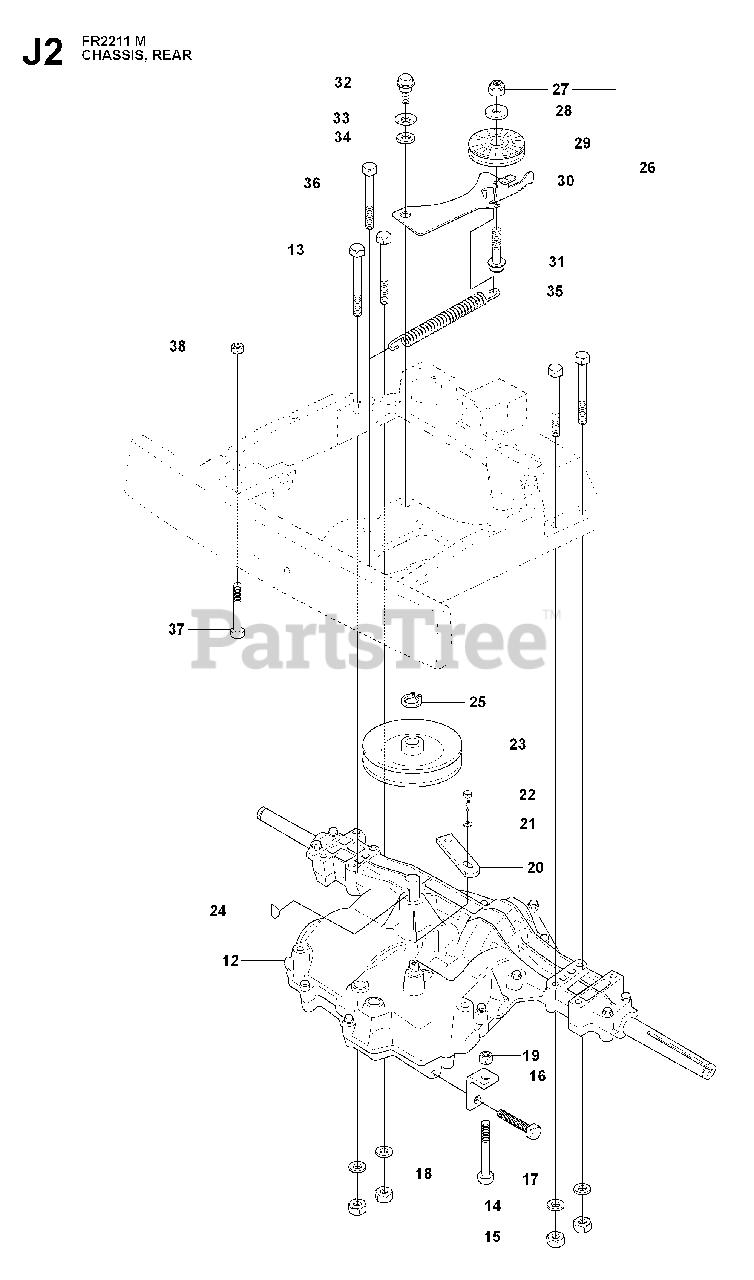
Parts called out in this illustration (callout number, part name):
14	WASHER BRB 8.4X17
15	NUT
16	WIRE BRACKET
19	NUT
21	WASHER
25	RETAINING RING SGA 16
27	LOCKNUT M8
33	SPRINGWASHER
34	WASHER - M12
38	NUT
